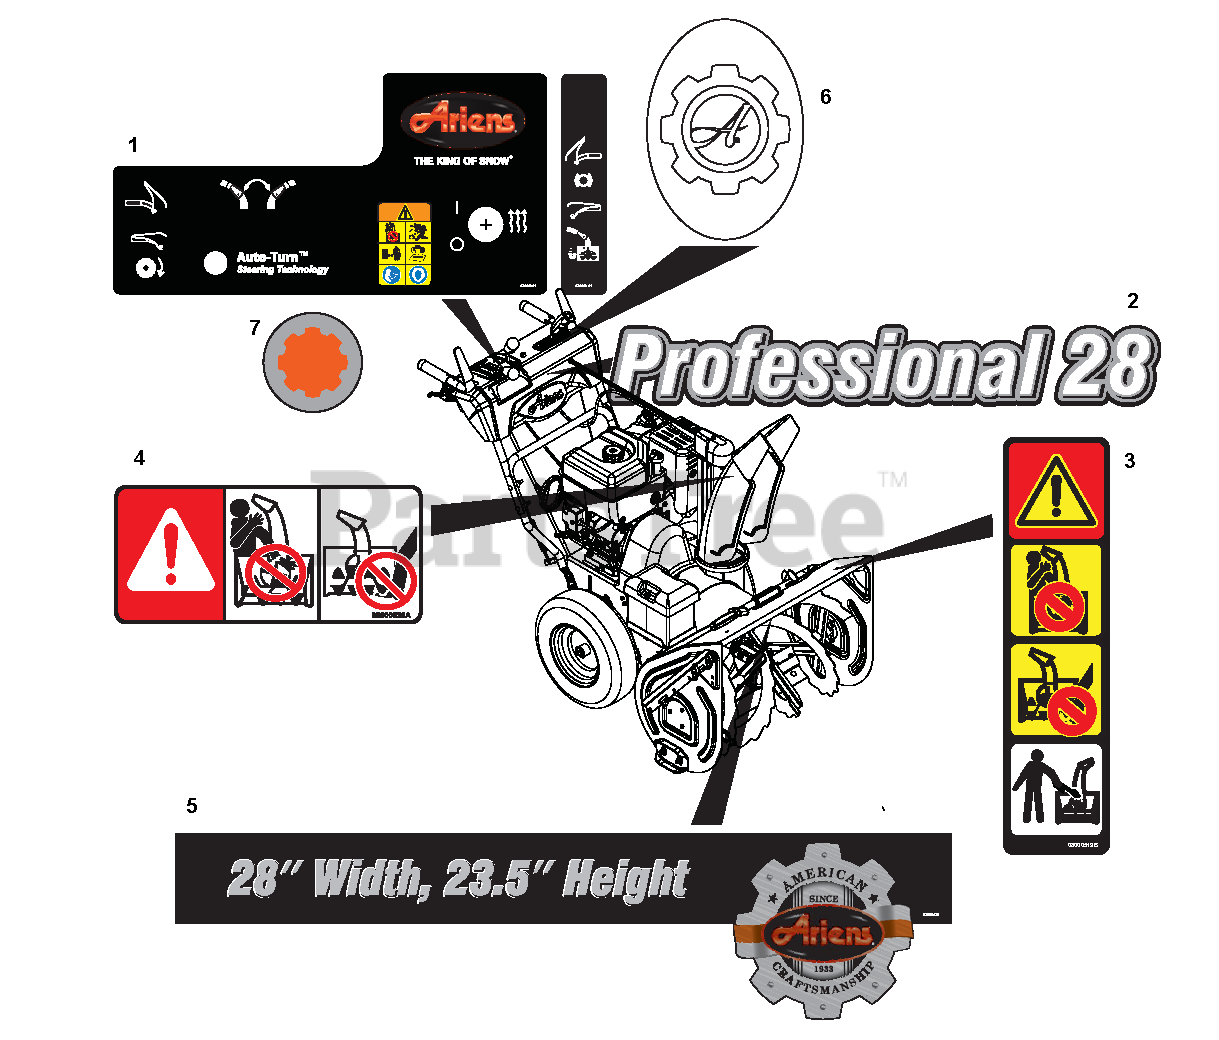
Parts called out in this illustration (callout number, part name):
1	DECAL, CONTROL PLATINUM/PRO
2	DECAL, PROFESSIONAL 28
3	DECAL, DANGER - ROTATING PARTS
4	DECAL, DANGER
6	DECAL, ARIENS GEAR - RAISED
7	DECAL,AUTODIFFERENTIAL
